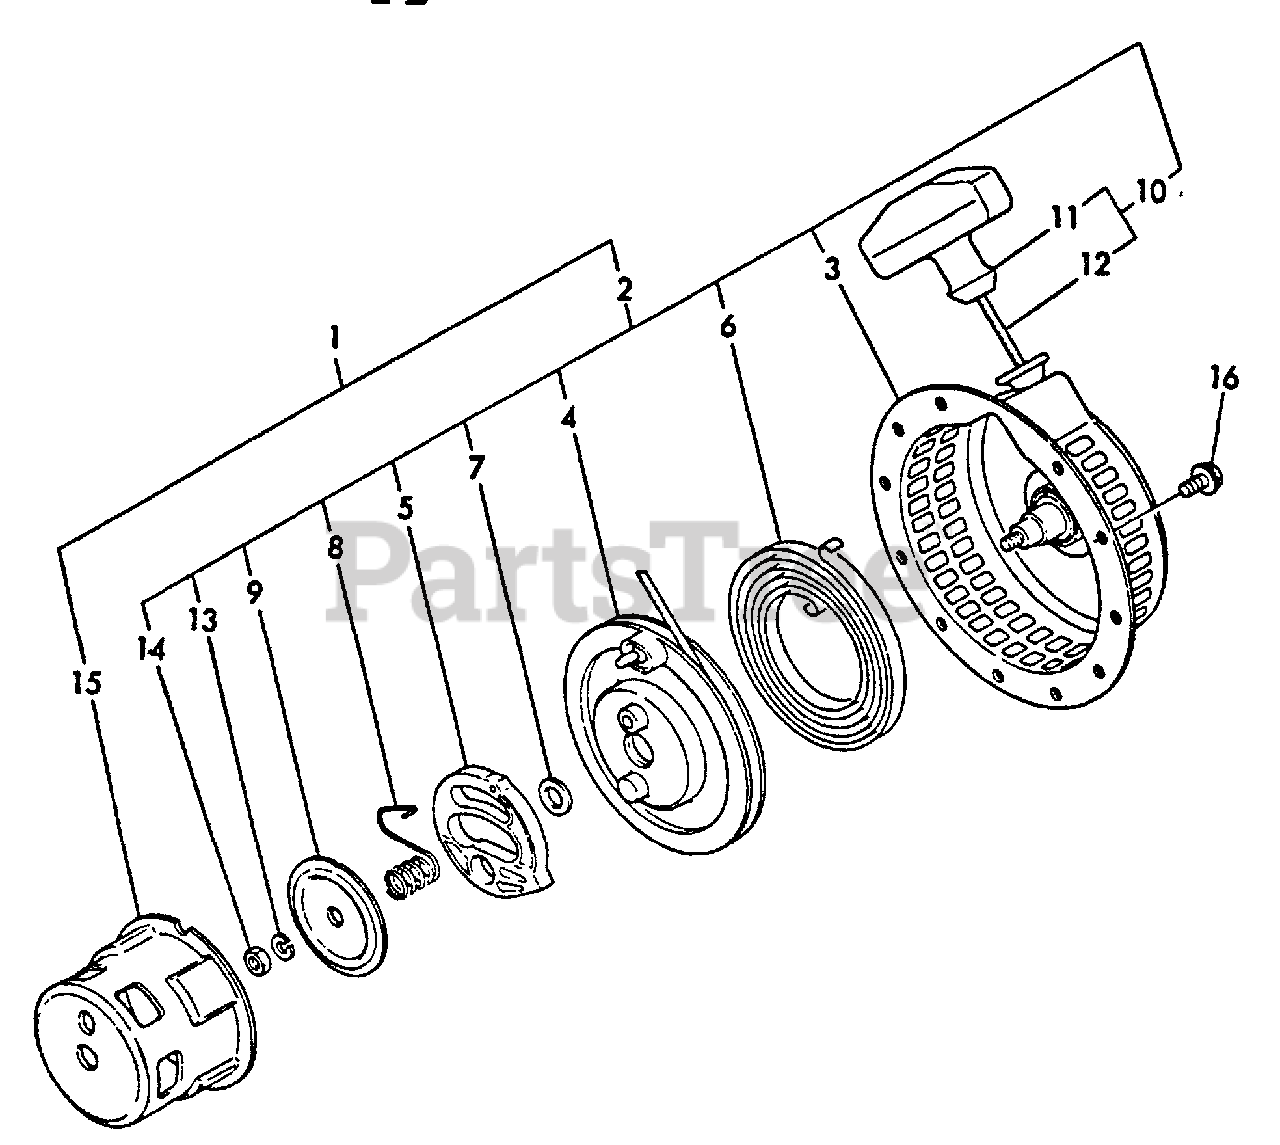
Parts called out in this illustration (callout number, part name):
1	STARTER ASSY
2	STARTER ASSY
3	CASE, STARTER
4	PULLEY
7	WASHER, THRUST
8	SPRING, FRICTION
9	PLATE, FRICTION
10	STARTER ROPE ASSY
11	GRIP, STARTER
12	ROPE, STARTER
13	LOCKWASHER - 6
14	NUT - 6
15	REEL, ROPE
16	BOLT - 6X12 -- PLATED
